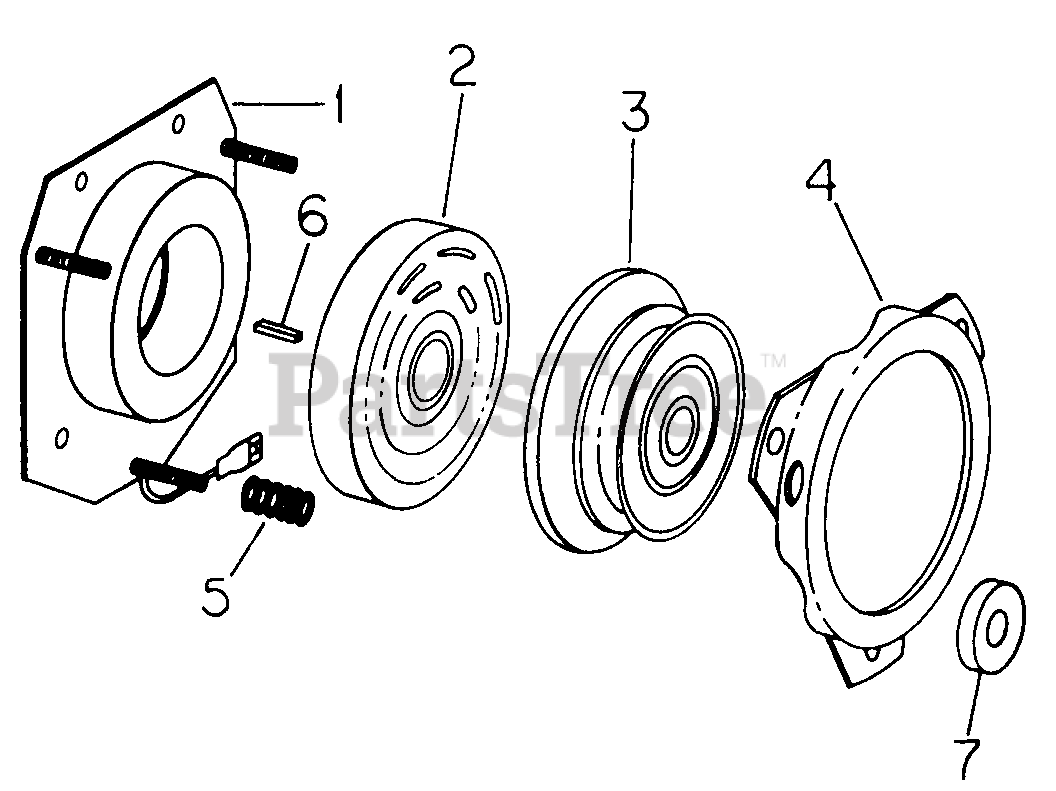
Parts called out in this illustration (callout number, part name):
5	Kit, Spring w/Nut
6	Key, 1/4 X .75 Sq Parallel
7	Washer, Weight Balance
